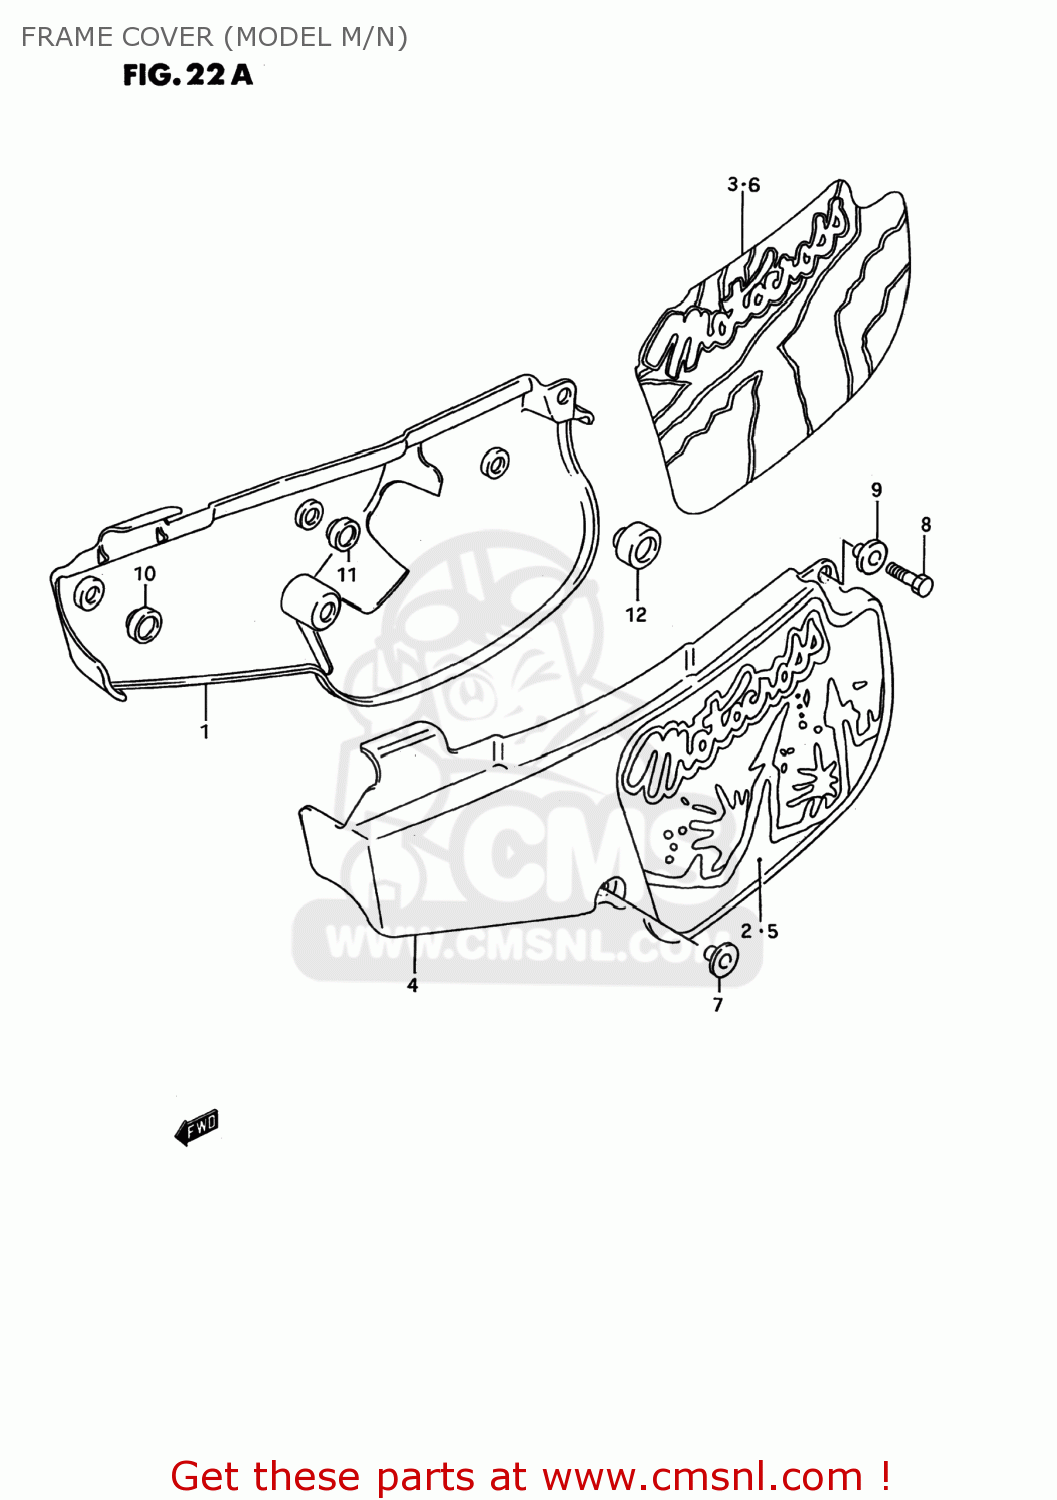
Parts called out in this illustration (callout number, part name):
1	COVER,SIDE,R(WHITE)
2	EMBLEM
3	EMBLEM
4	COVER,SIDE,L(WHITE)
5	EMBLEM,FRAME COVER
6	EMBLEM,FRAME COVER
7	WASHER
8	WASHER
9	BOLT
10	CUSHION
11	CUSHION
12	CUSHION
